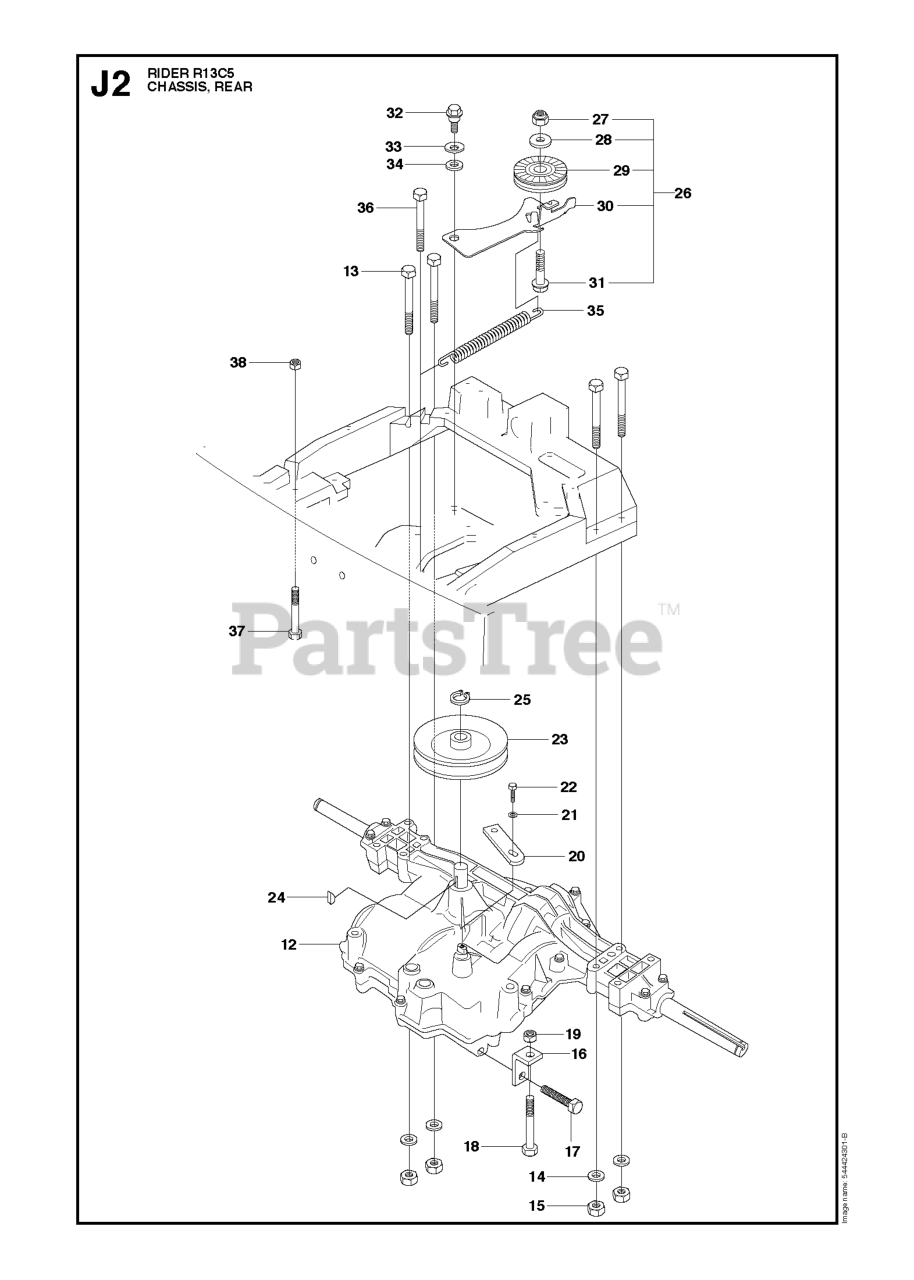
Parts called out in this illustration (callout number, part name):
14	WASHER BRB 8.4X17
15	NUT
16	Wire Bracket
18	SCREW
19	NUT
21	WASHER
25	Retaining Ring Sga 16
27	LOCKNUT M8
31	SCREW
33	SPRINGWASHER
34	WASHER - M12
35	SPRING
37	SCREW
38	NUT
